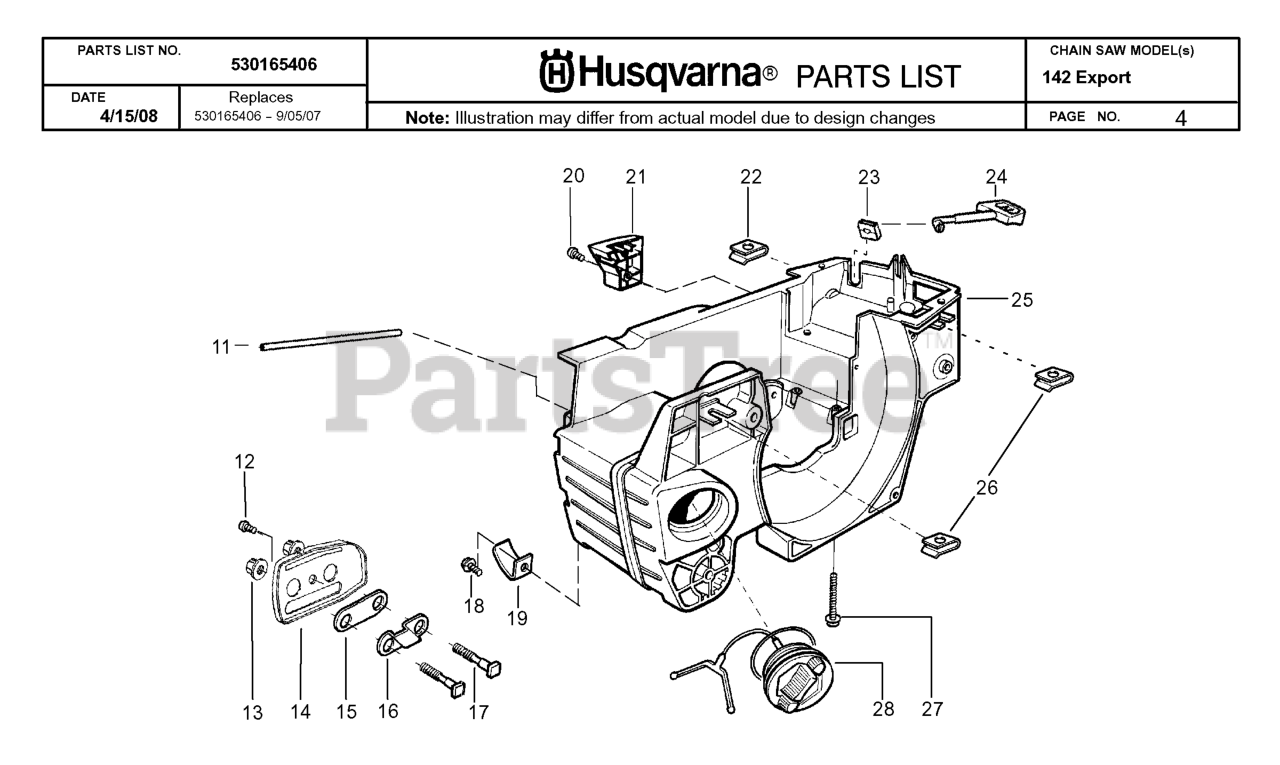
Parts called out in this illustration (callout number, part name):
15	OIL TANK GASKET
16	PLATE,BAR MOUNT
17	BAR BOLT 36/41
19	CHAIN CATCHER 36/41
21	LIMITER COVER
23	CHOKE GUIDE 36/41
24	CHOKE 36/41
25	KIT ASSY CHASSIS
27	SCREW M5-0.8X35M TAP
